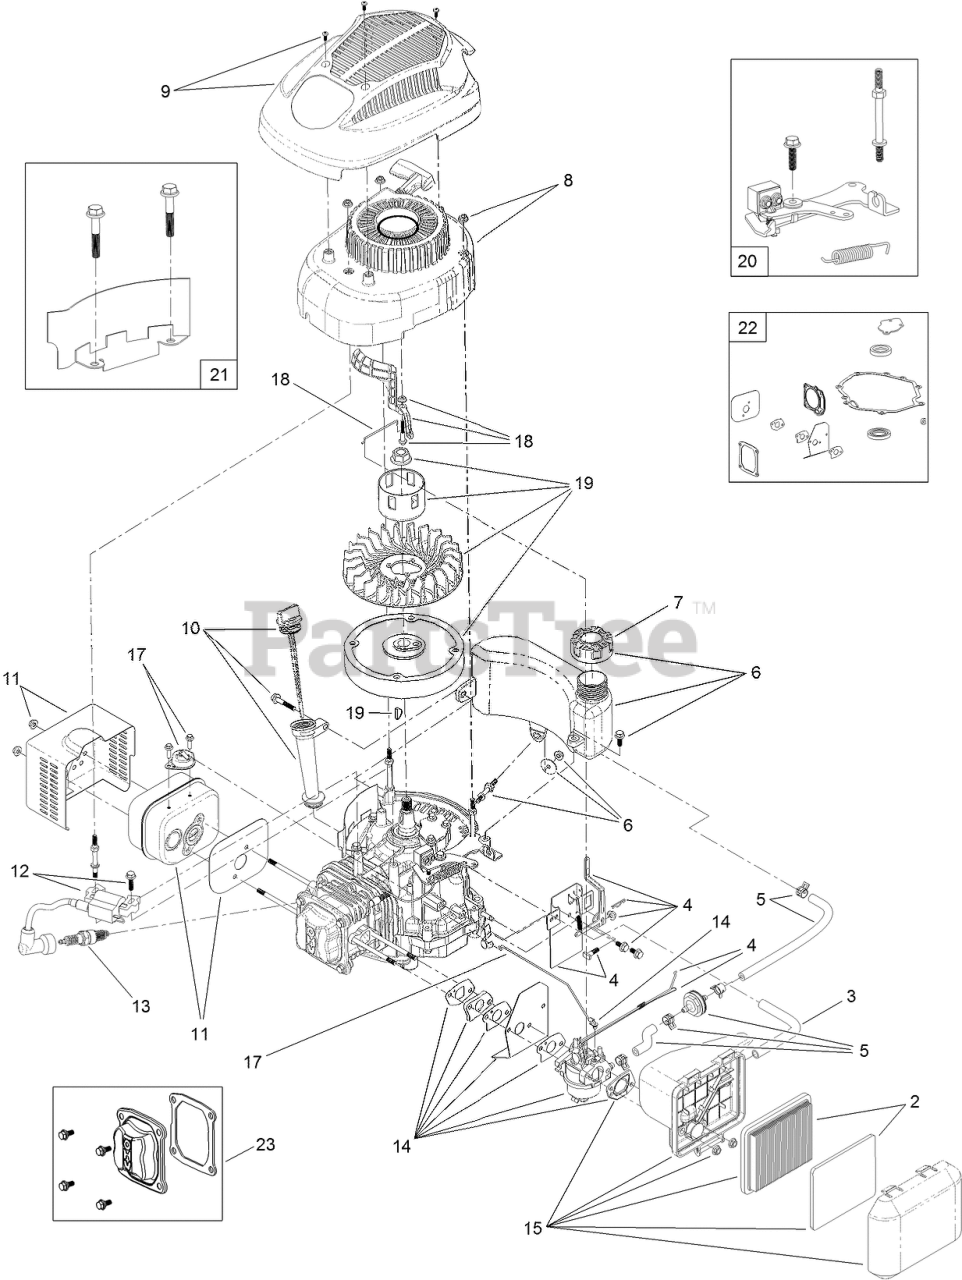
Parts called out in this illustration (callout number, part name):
2	AIR FILTER AND PREFILTER KIT
3	TUBE-BREATHER
4	GOVERNOR ARM KIT
5	FUEL LINE KIT
6	FUEL TANK KIT (CAP AND HARDWARE)
7	CAP-FUEL
8	SHROUD AND RECOIL ASM
9	STYLING SHROUD KIT
10	DIPSTICK AND FILL TUBE KIT
11	MUFFLER AND SHIELD KIT
12	IGNITION AND HARDWARE KIT
13	PLUG-SPARK
14	COMPETE CARB SERVICE KIT
14	CARBURETOR REPAIR KIT
15	AIR CLEANER ASM
17	THERMAL CHOKE CONTROL KIT
18	AIR VANE CHOKE KIT
19	FLYWHEEL AND FAN KIT
20	BRAKE ASM RECOIL KIT
21	FLYWHEEL SHIELD KIT
22	SEAL AND GASKET KIT
23	VALVE COVER KIT
